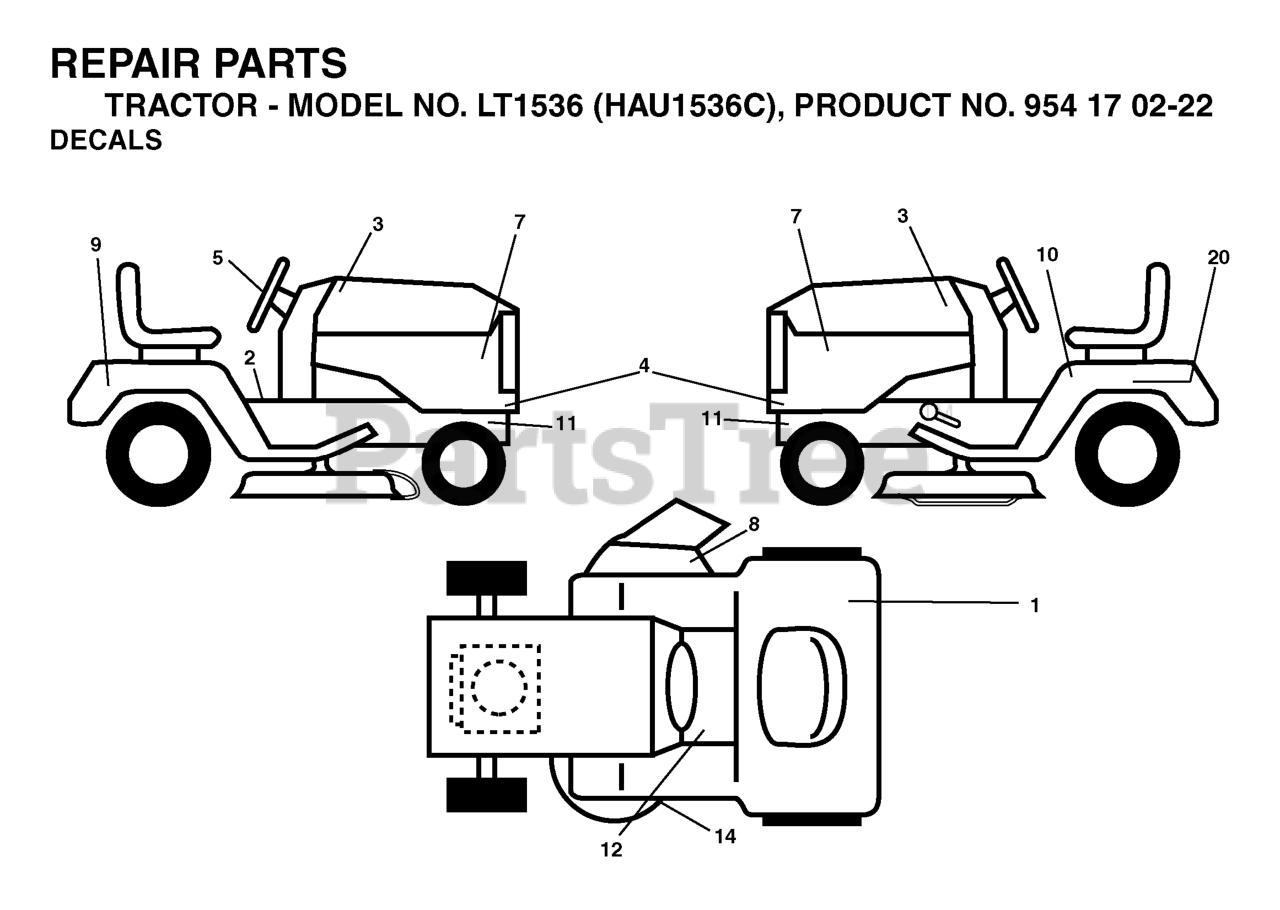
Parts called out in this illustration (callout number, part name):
1	DECAL
2	DECAL PARK BRAKE
5	DECAL.STEERING.HUSQ.BLUE
7	DECAL.HOOD.HUSQVARNA.INTERNATI
8	DECAL.INTERNATIONL.CUTFINGER
10	DECAL READ OWNER'S MAN SYMS
12	DECAL
14	DECAL V-BELT SCHEMATIC
20	DECAL BTRY SYMBOLS
